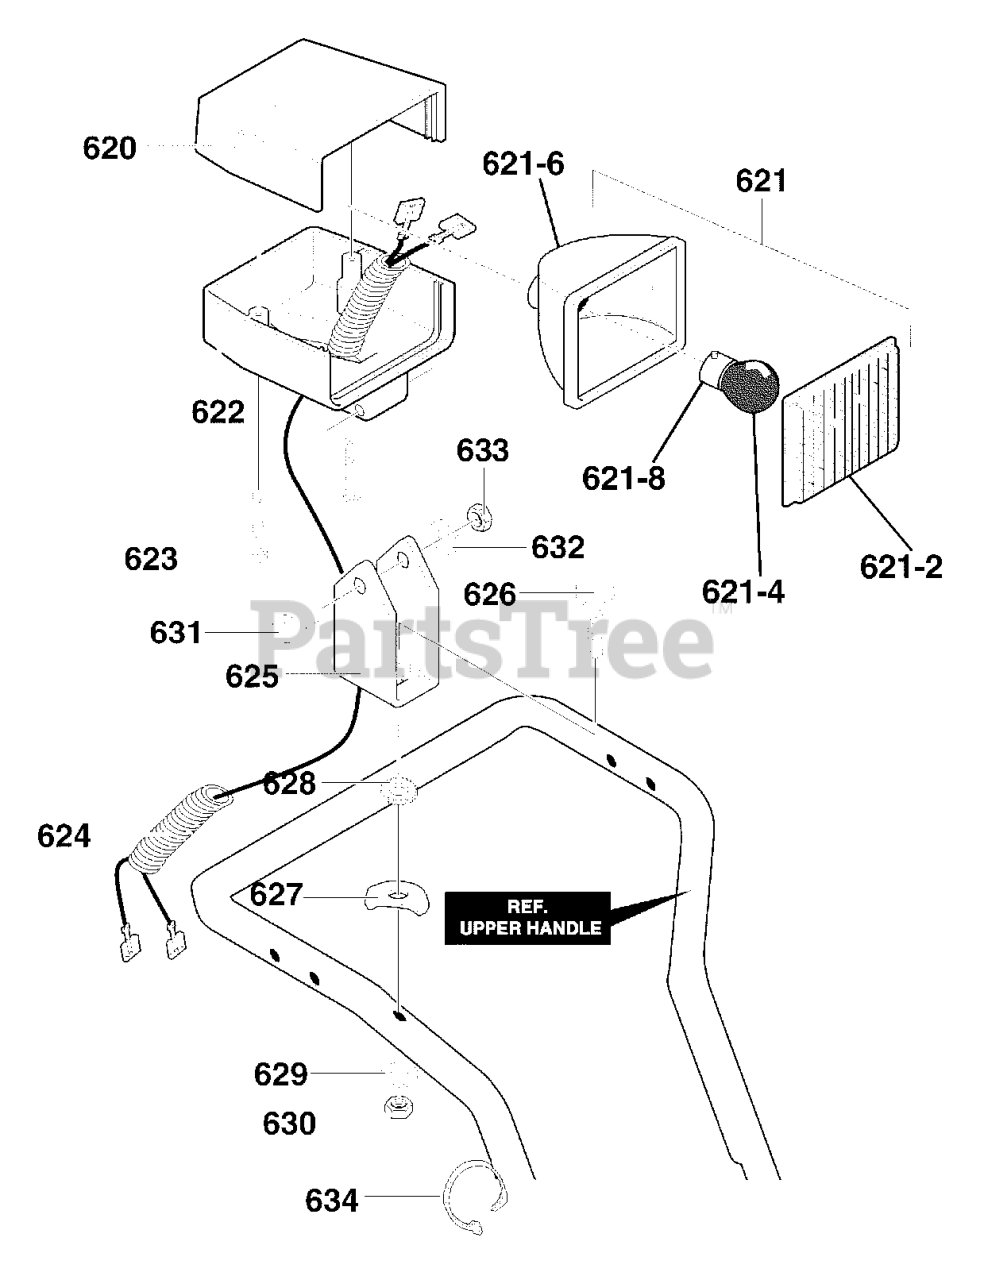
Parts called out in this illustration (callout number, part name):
620	HOUSING, HEADLIGHT UPPER
621	HEADLIGHT, ASSY
621-4	BULB 1156
621-6	BACK, METALIZED
622	HOUSING, HEADLIGHT LOWER
623	SCREW, #8X1.75
624	WIRING HARNESS
625	BRACKET, HEADLIGHT
626	BOLT, 5/16-18X1.75 CARR.
627	WASHER, SADDLE
628	WASHER, EXLK .32X.60X.040
629	WASHER, SPTLK .31X.58X.08
630	NUT, 5/16-18 REGHEX
631	SCREW, 5/16-18 x 2.00
632	WASHER, SPTLK
633	NUT, 5/16-18 REGHEX
634	TIE, CABLE
